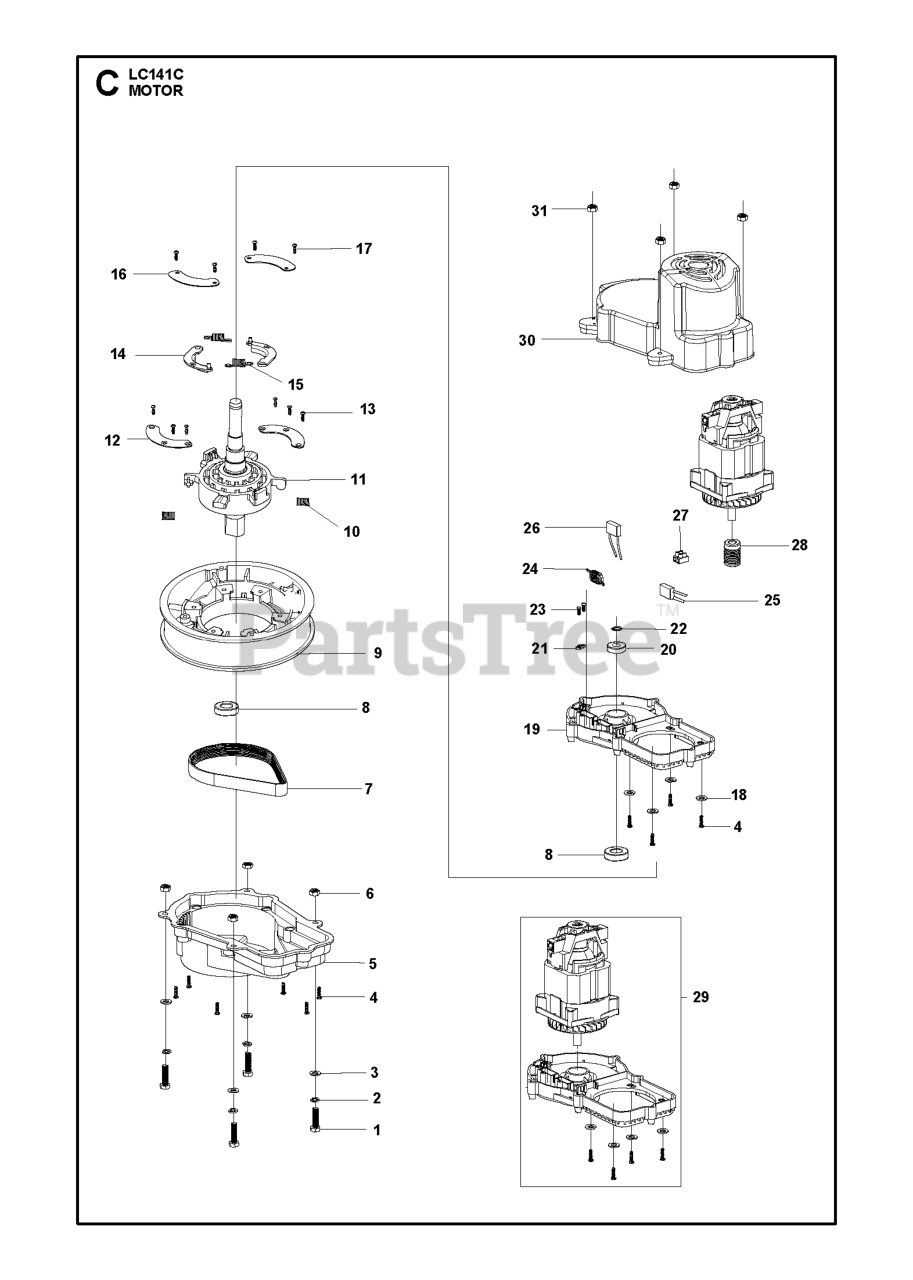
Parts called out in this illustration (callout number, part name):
2	SPRING WASHER
6	HEXAGON NUT #26800502301
31	NUT LOCKING
